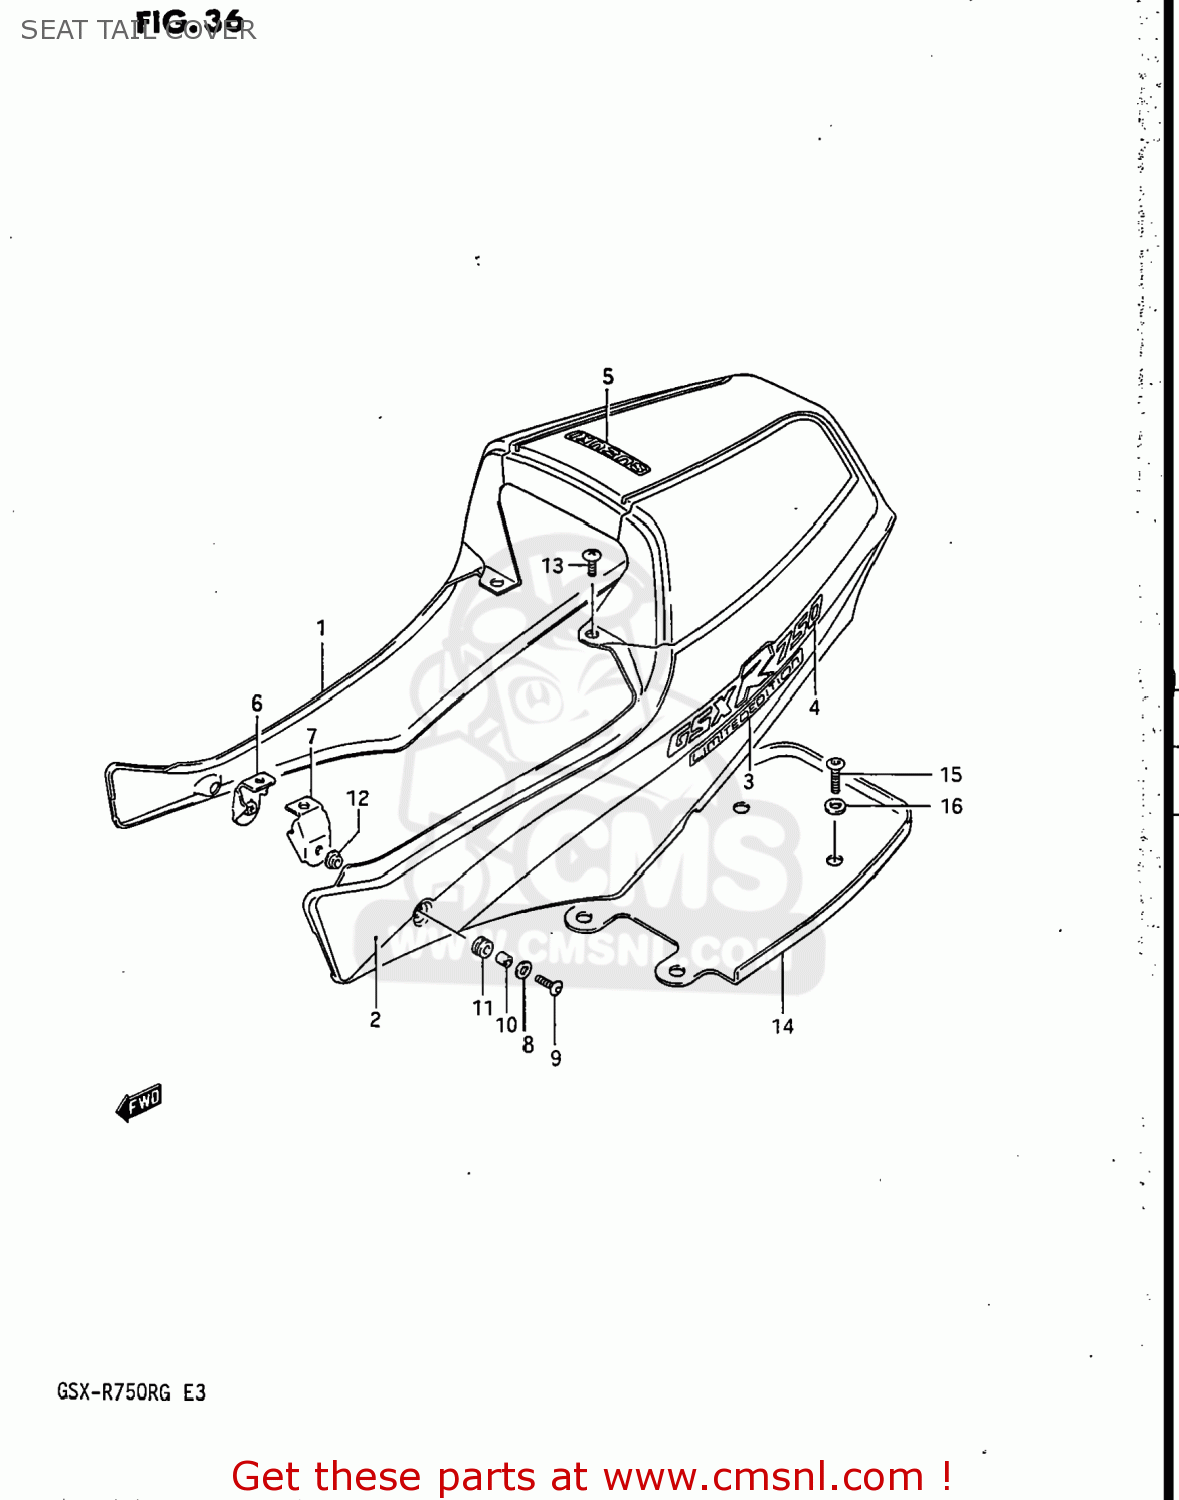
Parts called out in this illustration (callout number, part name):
1	COVER,SEAT TAIL
2	TAPE SET,BOX SEAT TAIL
3	EMBLEM (LIMITED EDITION)
4	EMBLEM,SEAT TAIL COVER
5	EMBLEM
6	HOLDER COMP,SEAT TAIL
7	HOLDER COMP,SEAT TAIL
8	WASHER(6.5X18X1)
9	SCREW(6X20)
10	SPACER
11	CUSHION
12	WASHER
13	SCREW
14	BOTTOM, SEAT TAIL
15	SCREW(6X16)
16	WASHER
